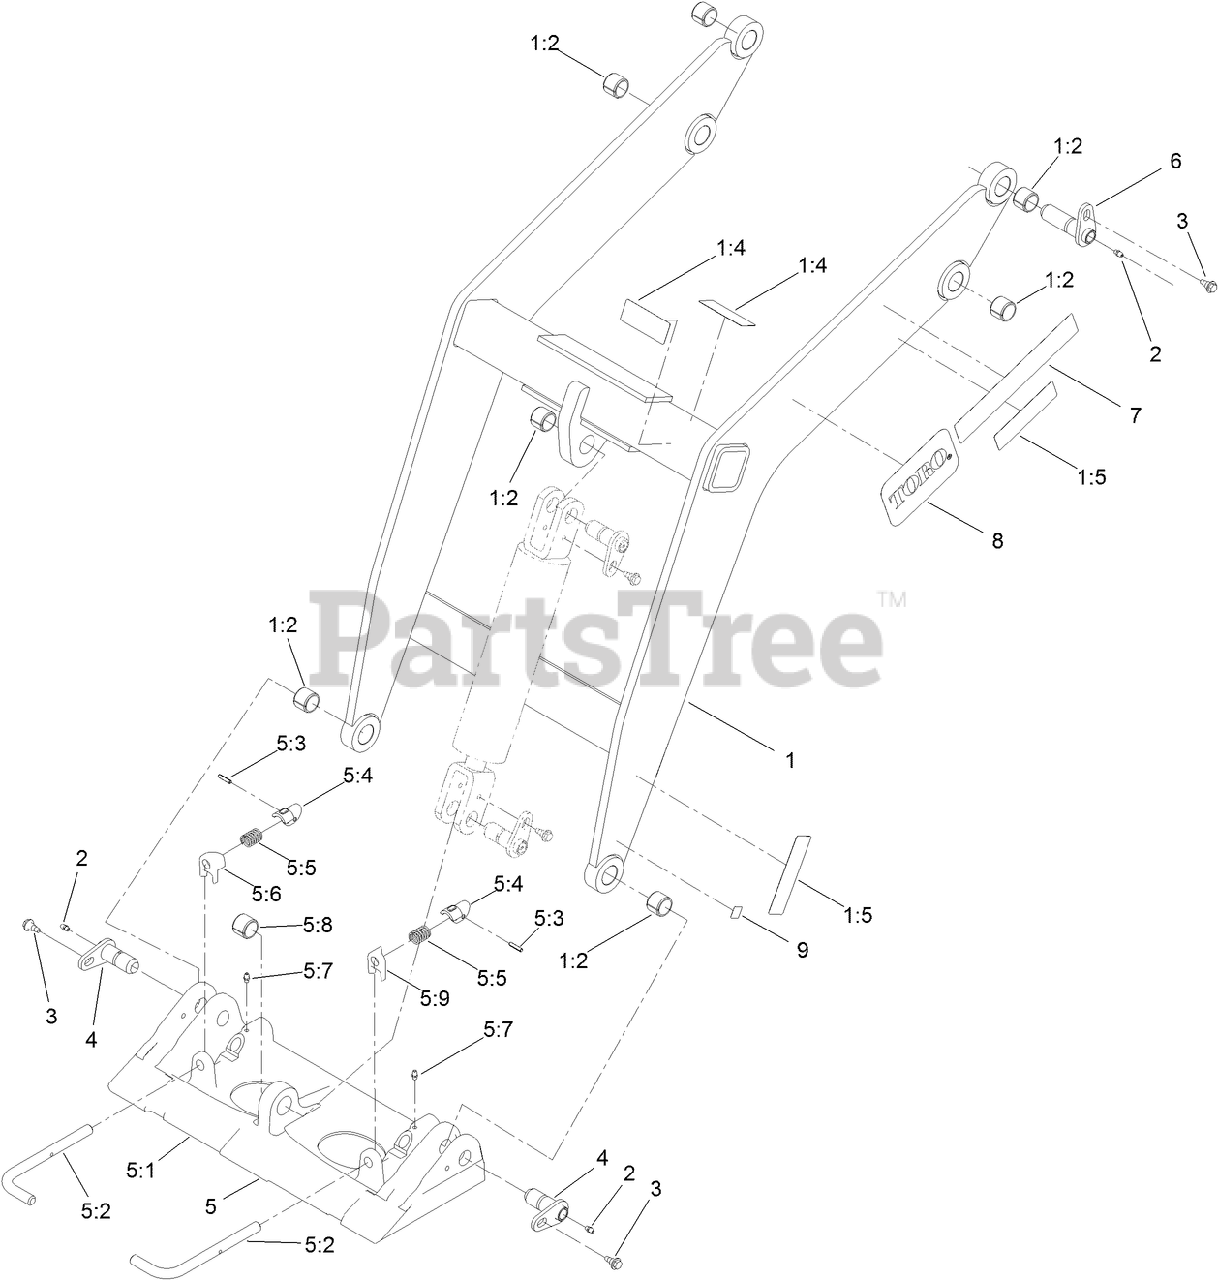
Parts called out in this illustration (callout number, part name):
1	LOADER ASM
1:2	BUSHING-TENSION
1:4	DECAL-WARNING, NO RIDER
1:5	DECAL-WARNING, CRUSHING
2	FITTING-GREASE
3	BOLT-SHOULDER
4	PIN-PIVOT
5	QUICK ATTACH ASM
5:1	MOUNT-QTACH
5:2	PIN-LOCKING
5:3	PIN-GROOVED
5:5	SPRING-COMPRESSION
5:6	STOP-RH
5:7	FITTING-GREASE
5:8	BUSHING-TENSION
5:9	STOP-LH
6	PIN-PIVOT
8	DECAL
9	DECAL-POINT, LIFT
